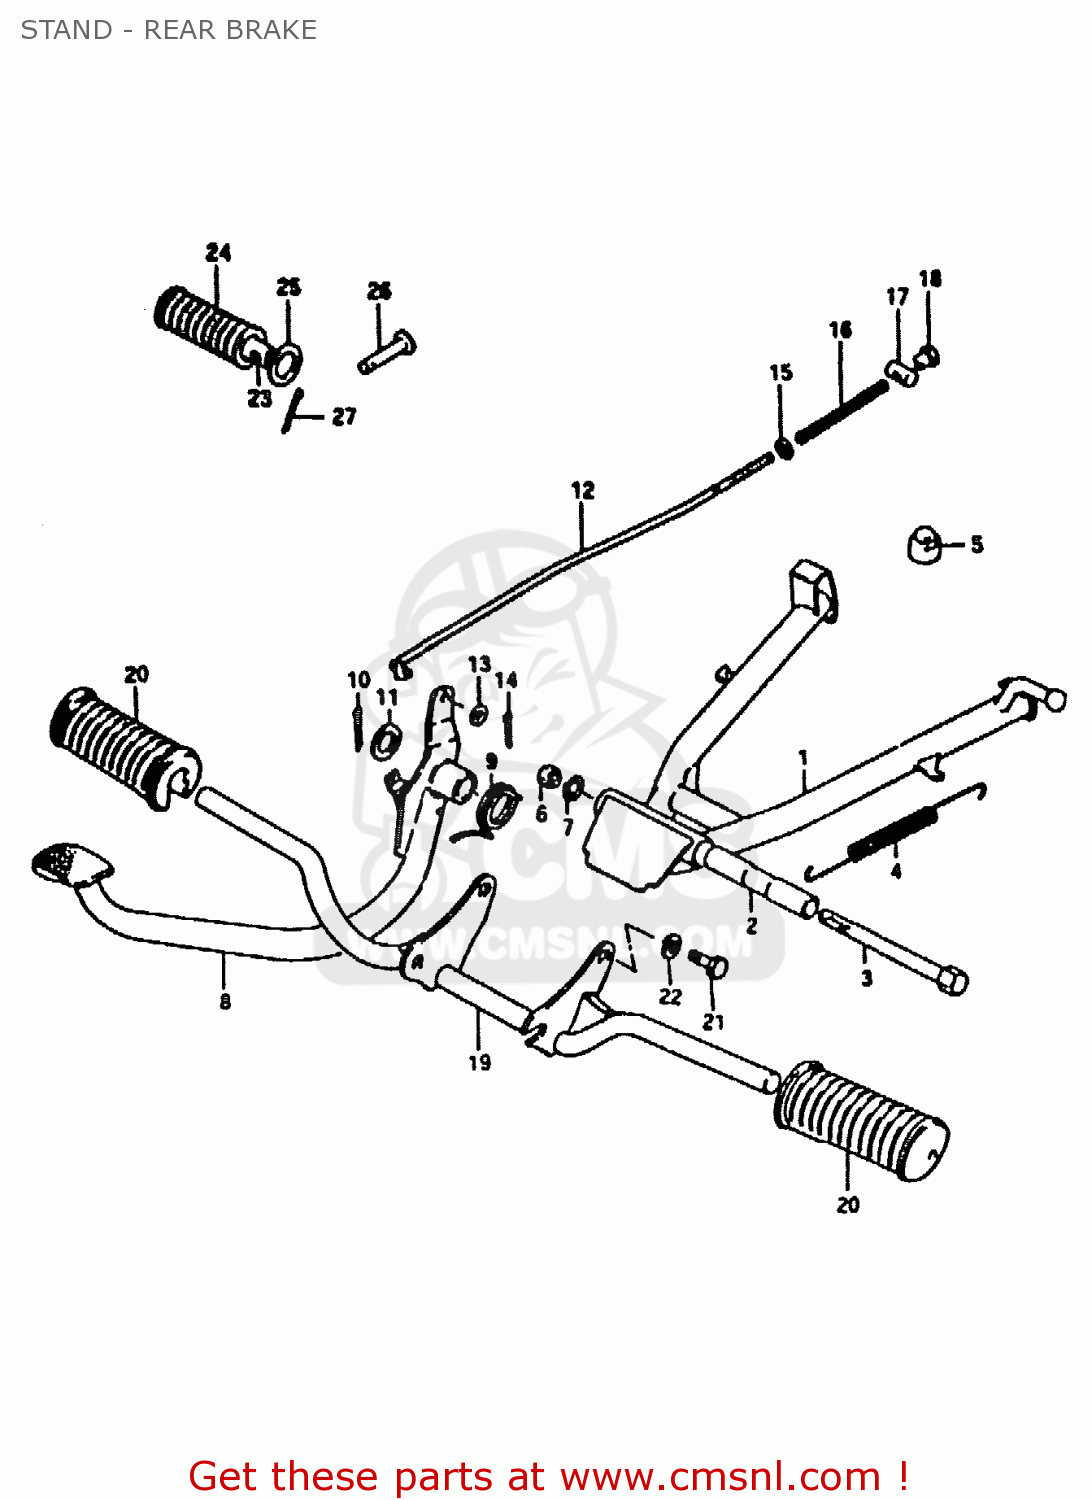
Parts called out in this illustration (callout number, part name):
1	STAND, CENTER
2	SPACER
3	BOLT(10X110)
4	SPRING
5	CUSHION
6	NUT
7	LOCK WASHER
8	PEDAL, BRAKE
9	SPRING
10	COTTER PIN
11	WASHER(15.5X26X2.3)
12	ROD ASSY,RR BRAKE
13	WASHER
14	PIN 20X20
15	WASHER
16	SPRING
17	PIN(11X18)
18	NUT
19	BAR, FRONT FOOTREST
20	RUBBER,FR FOOTREST
21	BOLT
22	LOCK WASHER
23	BAR,FOOTREST RUBBER
24	RUBBER,PILLION FOOTREST
25	WASHER (19.5X32X2)
26	PIN
27	PIN 20X20
